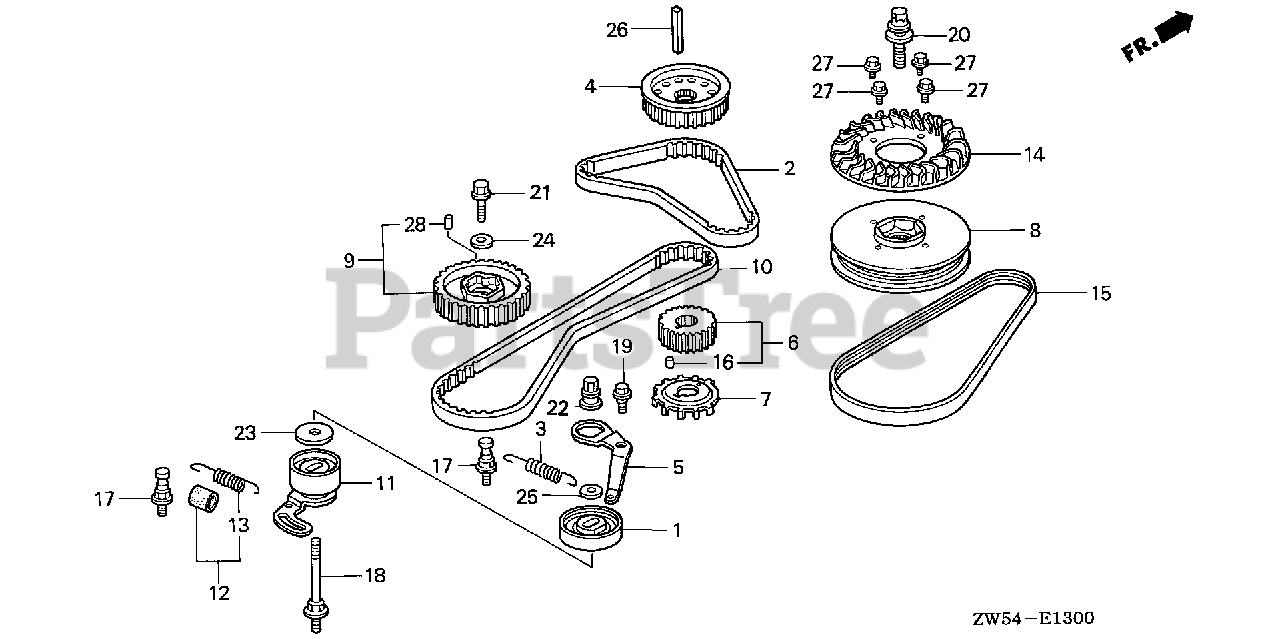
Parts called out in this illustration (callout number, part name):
1	TENSIONER, BALANCER BELT
2	BELT, BALANCER TIMING (UNITTA)
3	SPRING, BALANCER BELT ADJUSTER
4	PULLEY, BALANCER BELT DRIVE
5	BRACKET, B. BELT ADJUST
6	PULLEY, TIMING BELT DRIVE
7	PLATE, TIMING BELT GUIDE
8	PULLEY, CRANKSHAFT
9	PULLEY, TIMING BELT DRIVEN
10	BELT, TIMING (99RU24 B-333)
11	TENSIONER, TIMING BELT
12	SPRING, TIMING BELT ADJUSTER
13	SPRING, TIMING BELT ADJUSTER
14	FAN, COOLING
15	BELT, ALTERNATOR (4PK720 M150)
16	PIN, VERTICAL SHAFT
17	BOLT, TIMING BELT ADJUSTING SPRING
18	BOLT, TIMING BELT ADJUSTER
19	BOLT, BALANCER BELT ADJUSTER BRACKET
20	BOLT-WASHER (16X49)
21	BOLT, FLANGE (12X38)
22	NUT (10MM)
23	WASHER (10.5X44)
24	WASHER (12.5X34X5)
25	WASHER (10.3X25)
26	KEY (4.5X38.5)
27	BOLT, FLANGE (6X16)
28	ROLLER (4X10)
